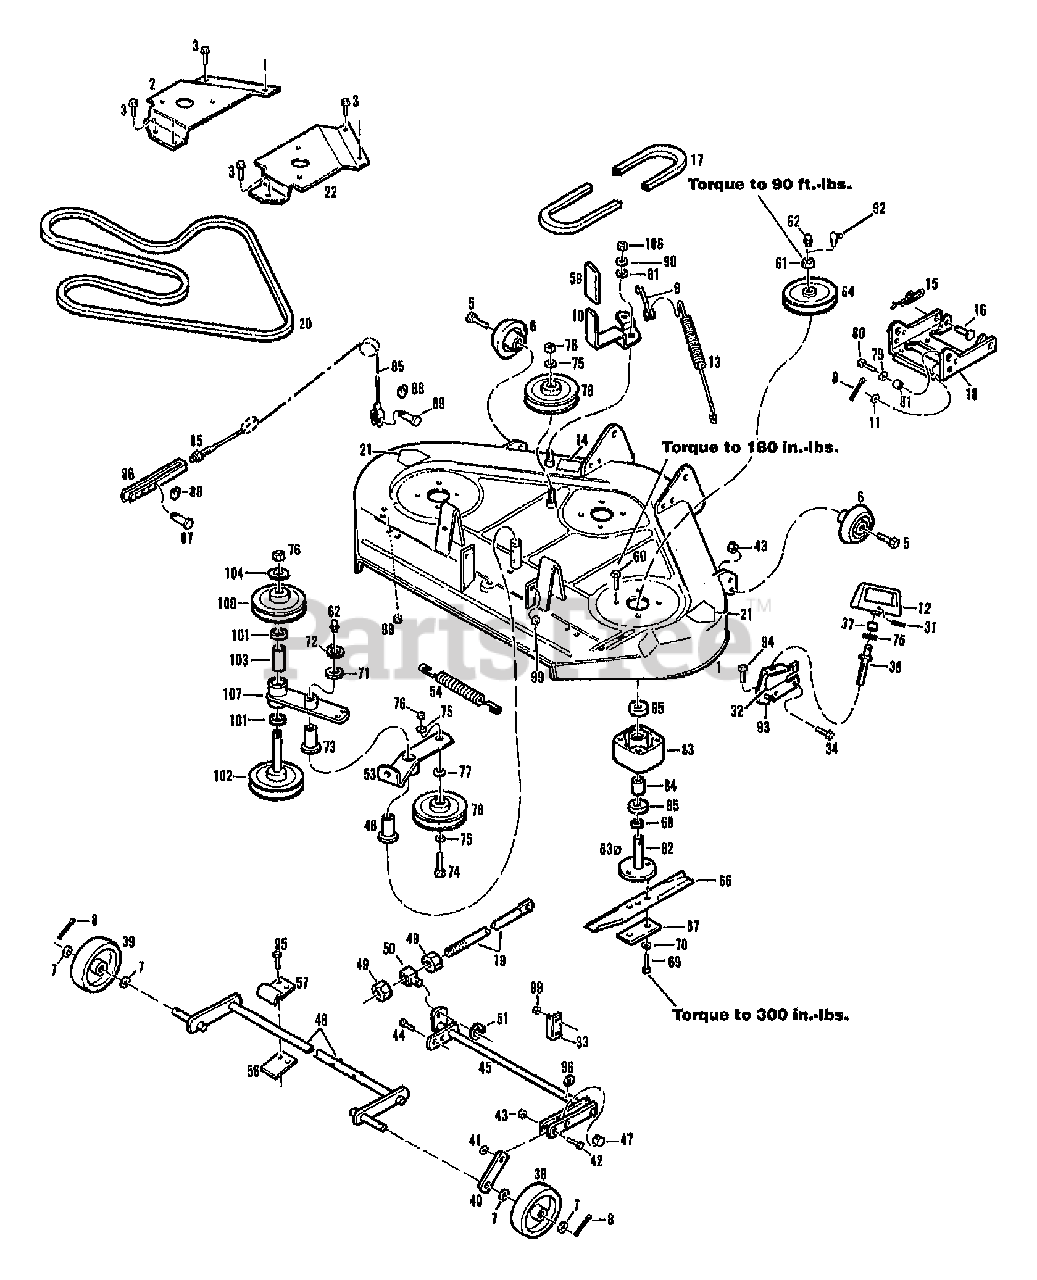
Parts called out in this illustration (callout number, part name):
1	ASSM-MOWER DECK W/DECAL
2	COVER-BELT LH
3	SCR 1/4-20X.5 FL SELF TAP
5	SCR-SHLDR 3/8-16
6	WHEEL-GAGE
7	WASHER-1.38 X.765X .06 ZP
8	PIN-COTTER .120X1.25 ZP
9	ROD-IDLER
11	WASHER-.5 DIA
12	HANDLE-HEIGHT ADJ
13	SPRING-EXTENSION
14	DECAL-BELT DRIVE
15	RING-COTTER
16	PIN-CLEVIS .62X2.50 ZP
17	BELT-V
18	ASSM-MOWER SUPPORT
19	ROD-ADJUSTER
21	DECAL-OPEI CAUTION
22	COVER-BELT RH
31	PIN-ROLL .188X1.0
32	DECAL-HEIGHT ADJUST
33	RETAINER-SHAFT
34	SCR-HH 5/16-18X.63 G5
37	SPACER-HANDLE
39	GAUGE-WHEEL
40	LINK-WHEEL SUPPORT
41	SPACER-.75X.39X.545
42	SCR-HH 3/8-16X1.5 G5 ZP
43	NUT-LOCK 3/8-16
44	SCR-HHC 5/16-18X.75 GR 5 ZP
45	ASSM-ARM HEIGHT ADJUST
46	ASSM-WHEEL SUPPORT
47	PIVOT-ADJUSTING SCR
48	BEARING-FLANGE
49	NUT-HEX
50	BLOCK-PIVOT
51	RING-RETAINING EXT .694 ID
54	SPRING-EXT
56	PLATE-DOUBLER
57	SUPPORT-SHAFT
60	SCR-HFLK 5/16-18X.75
61	NUT-H/LK
62	FITTING-GREASE 1/4-28X2.00
63	KEY-WOODRUFF .188X.75
65	BEARING-BALL
66	BLADE-42" GRS DECK
67	PLATE
68	WASHER N/A
69	SCR-HH 3/8-24X1.0 G5 ZP
70	WASHER-LK .375 @ DEPL
71	SHIM-WASHER
72	RING-RET. EXT .875 ID
73	FLANGE-BEARING
74	SCR-HH 1/2-13X2.0 G5 ZP
75	WASHER-FLAT .88X.5X.06 ZP
76	NUT-TOP LOCK 1/2-13 ZP
78	PULLEY-IDLER
79	WASHER
80	SCR-HH 1/2-13X1.25 G5 ZP
81	SPACER-TUBULAR
82	ASSM-BLADE SHAFT
83	HOUSING-SPINDLE
85	ASSM-CABLE(MOWER DECK)
86	YOKE
87	PIN-CLEVIS .5X1.437 ZP
88	RING-CIRCLE COTTER
89	PIN-CLEVIS .375 X .937 ZP
90	WASHER-.875X.390X.134
91	WASHER-FLAT 1.0X.516X.031
92	FITTING-GREASE 90 DEGREE
93	ASSM-WHEEL BRKT
94	SCR-HH 3/8-16X1.0 G5 ZP
95	SCR-HH 5/16-18X1.25 G5ZP
96	WASHER-PLASTIC
99	NUT-TOP/LK 5/16-18 ZP
100	ASSM-SHEAVE & HUB
101	BEARING-BALL
102	ASSM-SHEAVE & SHAFT
106	NUT-H/LK 3/8-24
107	ASSM-MOUNTING ARM
